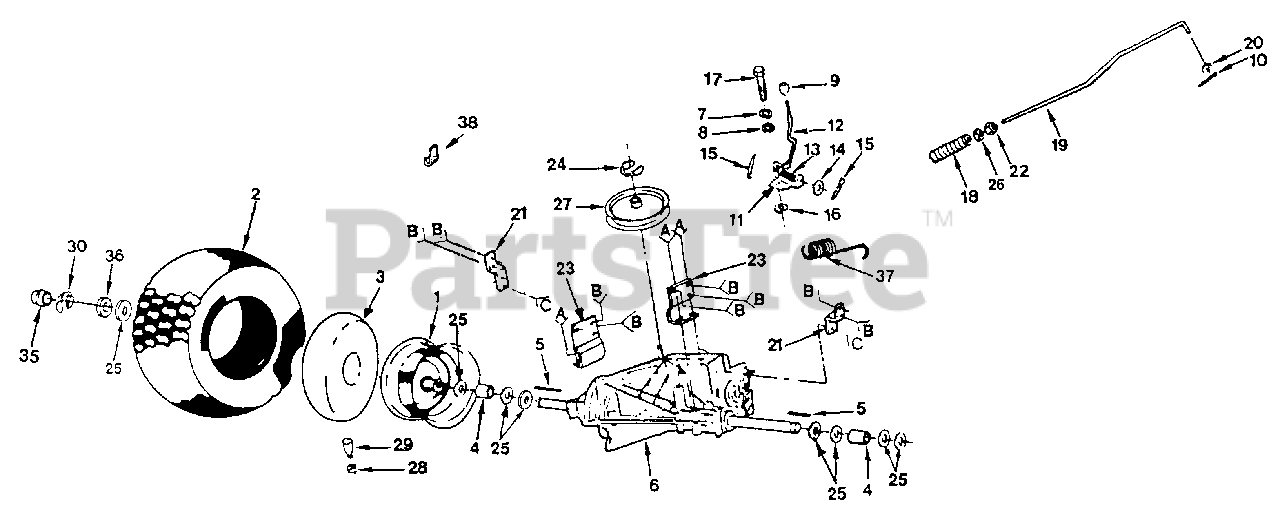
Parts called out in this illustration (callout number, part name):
1	Rim Assembly - 8" Rear
2	Tire 18 x 9.50 - 8" (Tubeless)
3	Tube, Tire
4	Spacer, Split
5	Key, Square 2.5 x .1845/.1865
6	6 Speed Heavy Duty Transaxle
7	Washer, Lock 1/4
8	Washer 9/32 x 3/4 x 10 Ga.
9	Knob, Control
10	Cotter Pin 1/8 x 3/4
11	Plate, Rod, Shift
12	Rod, Shifter
13	Spring, Torsion
14	Washer 15/32 x 3/4 x 16 Ga.
15	Pin, Cotter 1/8 x 1
16	Washer, Shift Plate
17	Bolt, Hex 1/4-28 x 3/4 Gr. 8
18	Spring, Rod, Brake
19	Rod, Brake
20	Washer 13/32 x 13/16 x 16 Ga.
21	Strap, Torque
22	Nut, Hex Jam 3/8-16
23	Bracket, Transaxle
24	Ring, Retainer
25	Washer 25/32 x 1-1/4 x 16 Ga.
27	Pulley, Input Transaxle
28	Cap, Valve
29	Stem, Valve
35	Cap, Hub, Rear
36	Washer 25/32 x 1-5/8 x 16 Ga.
37	Spring, Brake Return
38	Clip, Fuel Line
